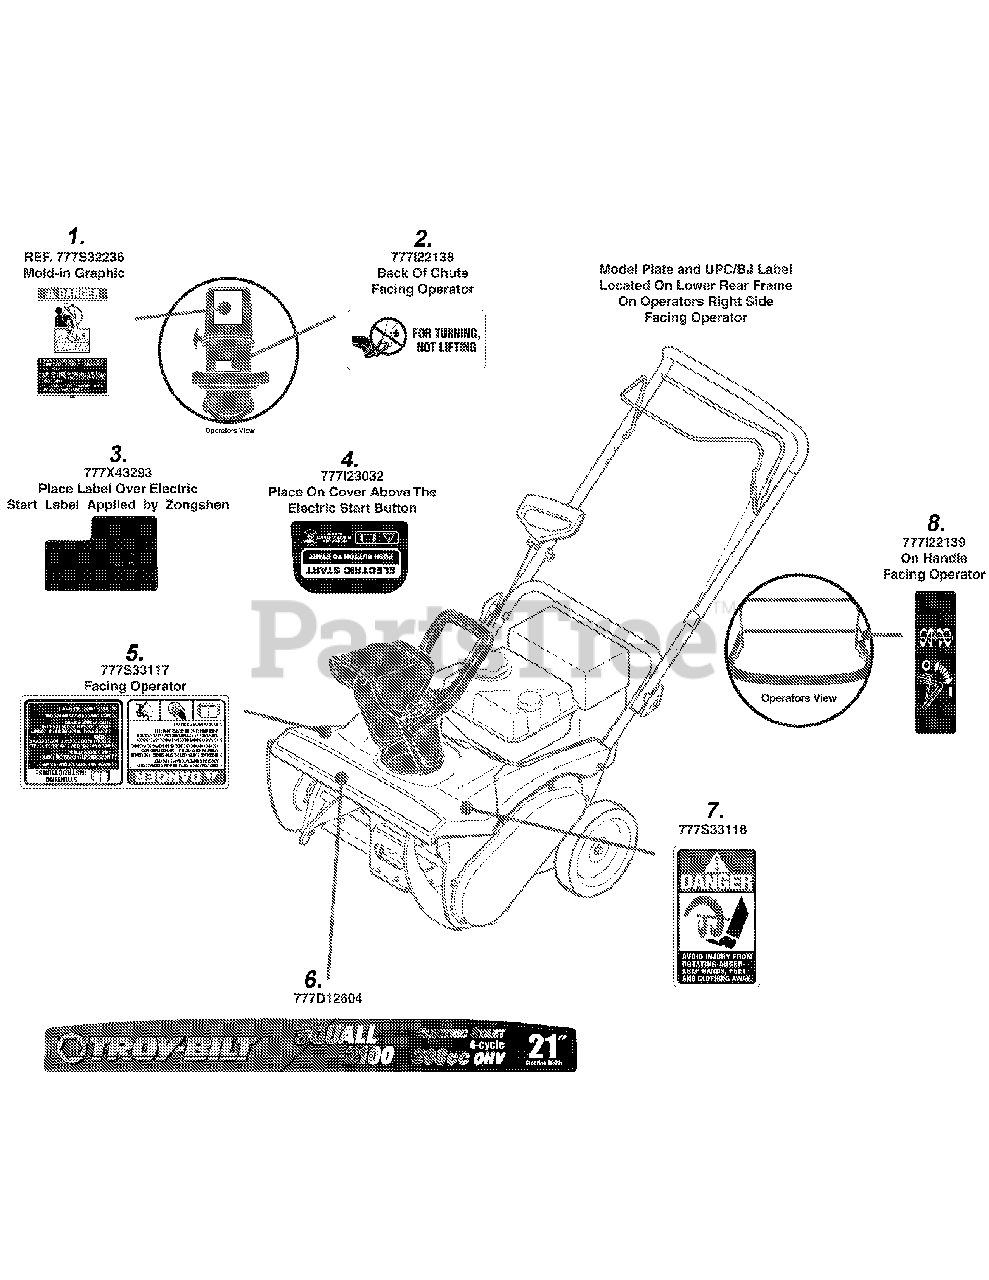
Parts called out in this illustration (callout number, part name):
1	LABEL-SNOW CHUTE
2	LABEL-CHUTE
3	LABEL-SNOW:SS EL START PATCH:BLK
4	LABEL-SNOW ELEC START
5	LABEL-SNOW
6	LABEL-SNOW FRONT SQUALL
7	LABEL-SNOW FRONT AUGER DANGER
8	LABEL-SNOW:HANDLE
